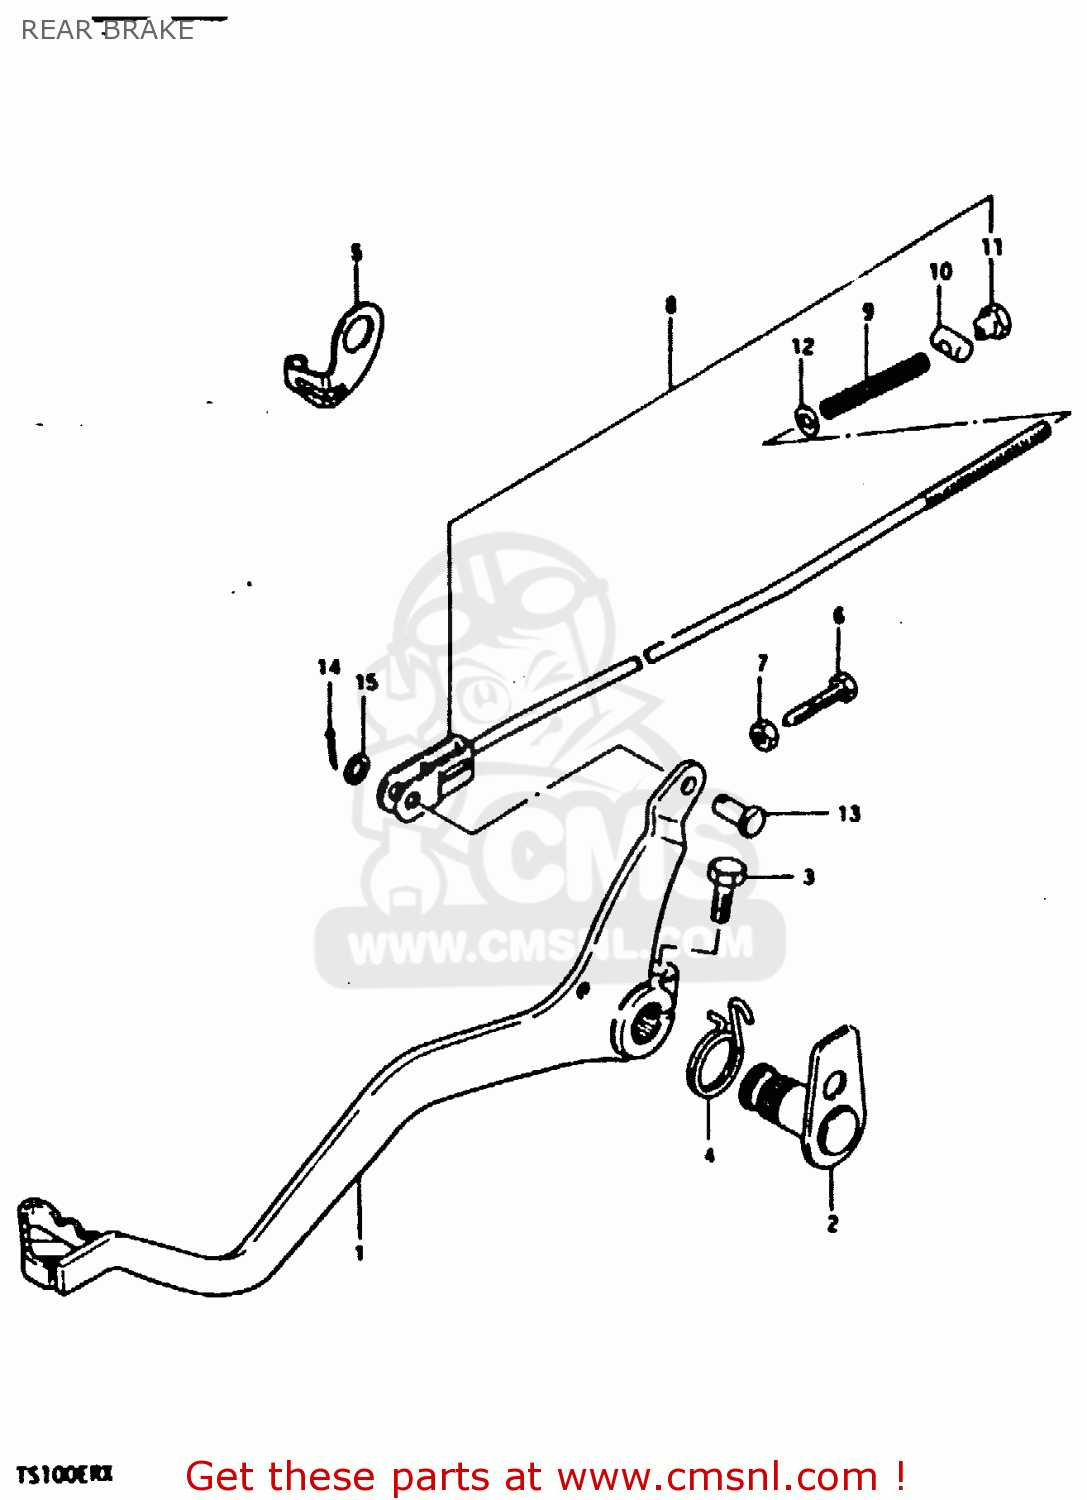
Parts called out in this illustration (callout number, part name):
1	PEDAL,BRAKE
2	ARM,BRAKE PEDAL
3	BOLT
4	SPRING
5	HOOK,STOP LAMP SWITCH SPRING
6	BOLT(6X23)
7	NUT
8	ROD ASSY,RR BRAKE
9	SPRING
10	PIN
11	NUT
12	WASHER
13	PIN(L:13.5)
14	PIN 20X20
15	WASHER
